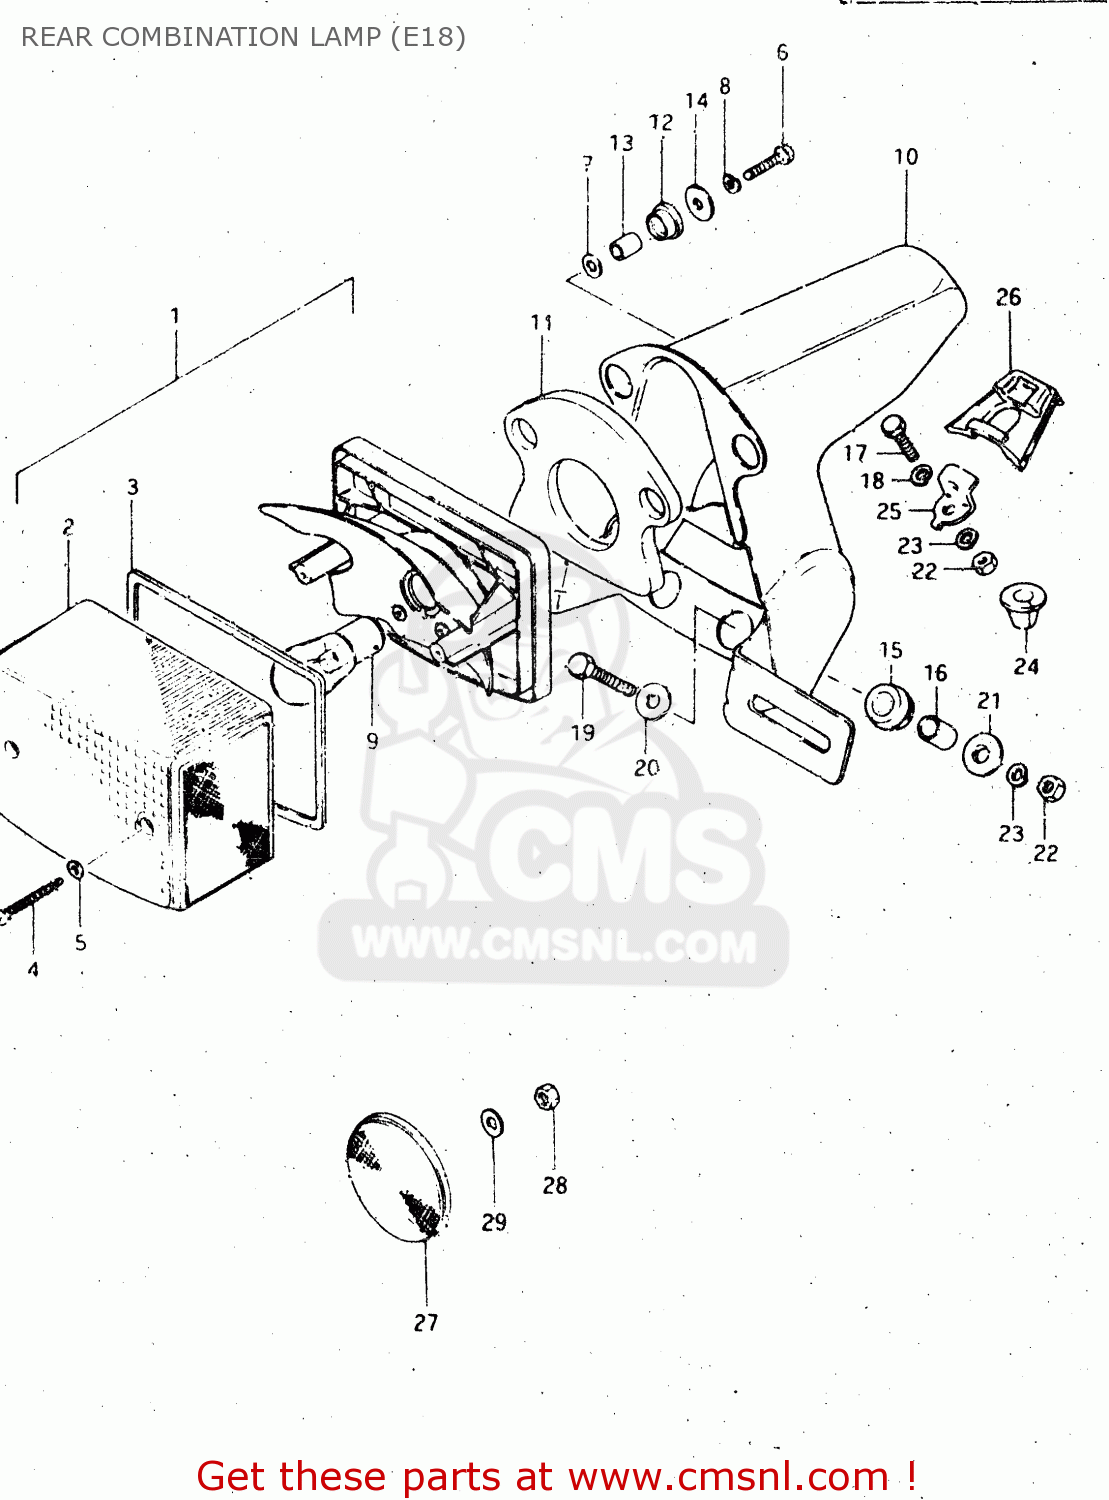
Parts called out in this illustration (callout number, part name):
1	LAMP UNIT,RR COMBNATION
2	LENS,RR COMBINATION
3	GASKET (NAS)
4	SCREW
5	GASKET (NAS)
6	SCREW
7	WASHER
8	LOCK WASHER
9	BULB (6V,21/5W)
10	BRACKET ASSY
11	CUSHION,REAR COMBINATION LAMP
12	CUSHION,REAR COMBINATION LAMP
13	SPACER,REAR COMBINATION LAMP
14	WASHER,REAR COMBINATION LAMP
15	CUSHION,REAR COMBINATION LAMP
16	SPACER
17	BOLT
18	LOCK WASHER
19	BOLT
20	WASHER (6.5X20X1.2)
21	WASHER
22	NUT
23	WASHER, LOWER
24	GROMMET
25	PLATE
26	CUSHION
27	REFLECTOR,REFLEX
28	NUT
29	WASHER
